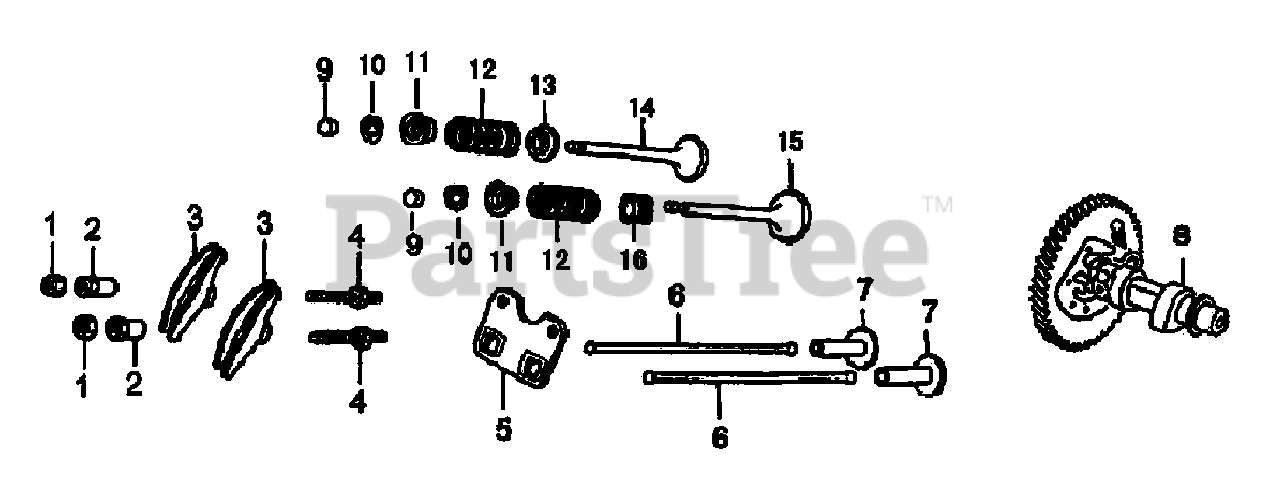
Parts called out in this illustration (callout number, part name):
1	NUT, PIVOT ADJUSTING
2	PIVOT, ROCKER ARM
3	ARM, ROCKER
4	BOLT, PIVOT
5	PLATE ASSY.
6	ROD, PUSH
7	LIFTER, VALVE
8	CAMSHAFT ASSY.
9	ROTATOR, VALVE
10	LOCKER, VALVE
11	RETAINER, EX. VALVE SPRING
12	SPRING, VALVE
13	SEAT, VALVE SPRING
14	VALVE, EXHAUST
15	VALVE, INTAKE
16	SEAL, VALVE STEM
